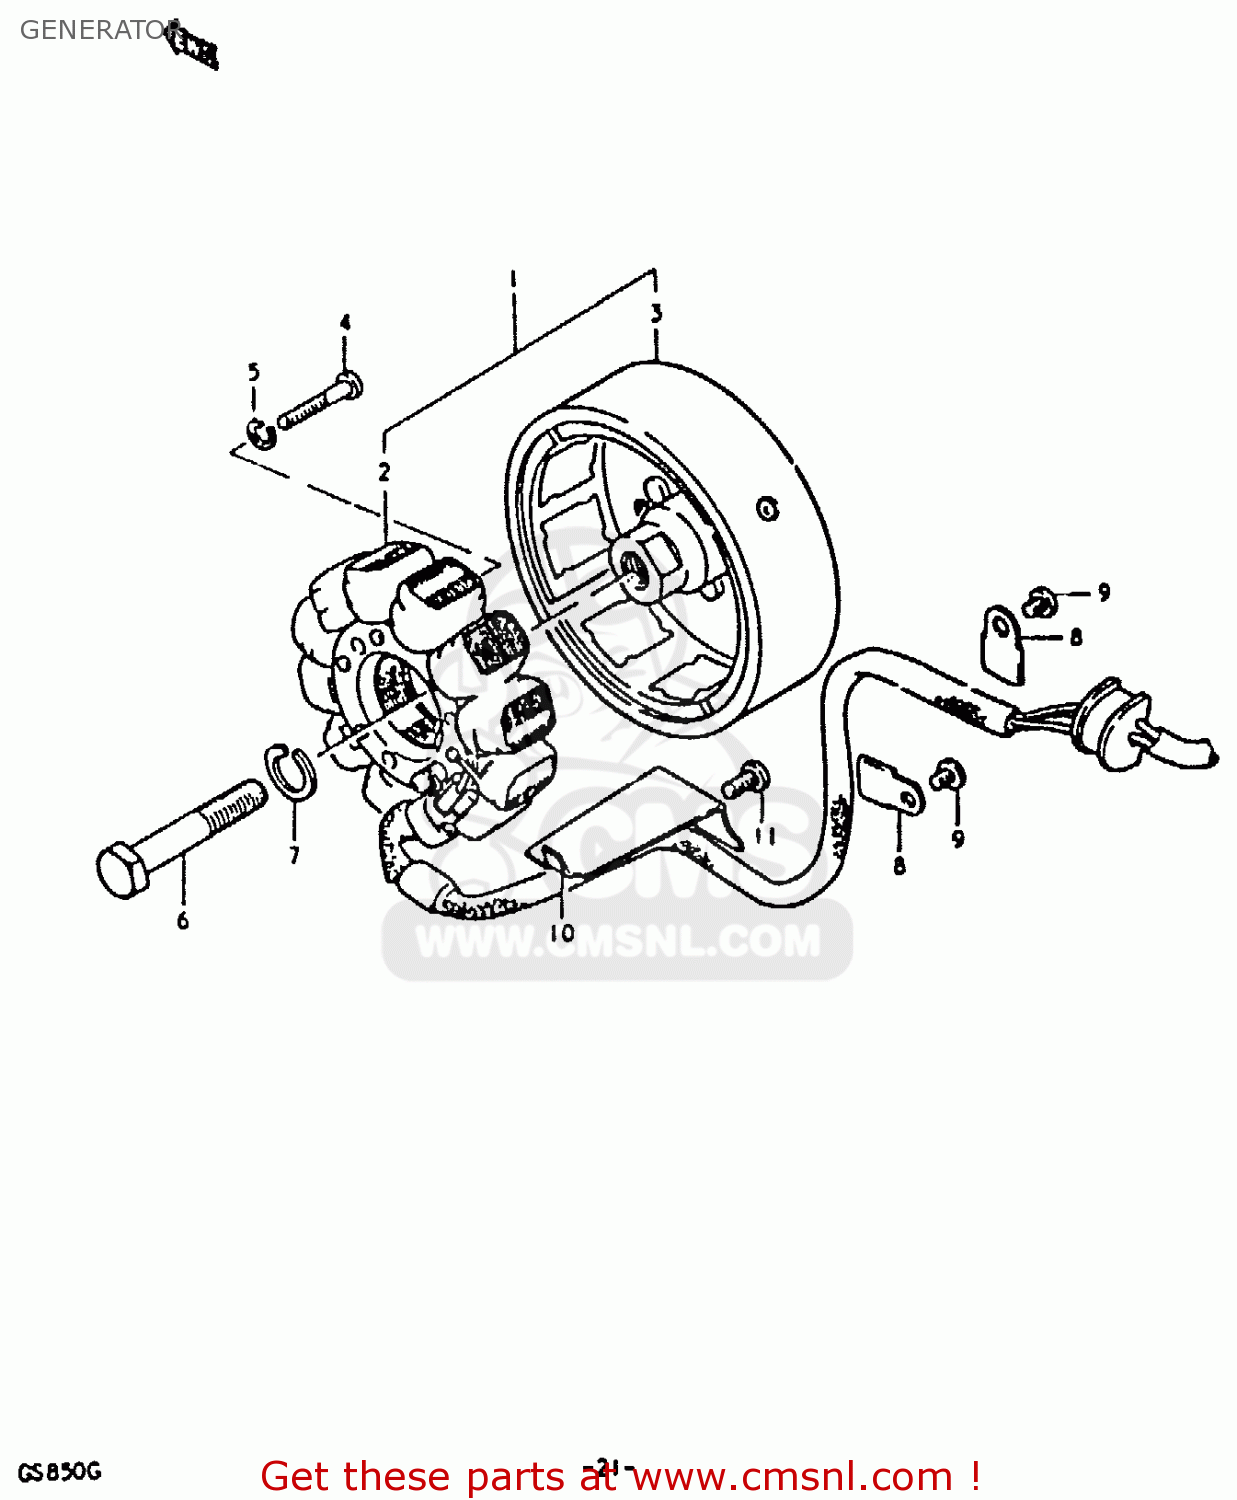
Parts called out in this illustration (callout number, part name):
1	GENERATOR ASSEMBLY
2	STARTER ASSY
3	ROTOR ASSEMBLY
4	SCREW
5	LOCK WASHER
6	BOLT 12X45
7	WASHER,LOCK 12
8	CLAMP,GENERATOR LEAD WIRE
9	SCREW
10	CLAMP,GENERATOR LEAD WIRE
11	SCREW
